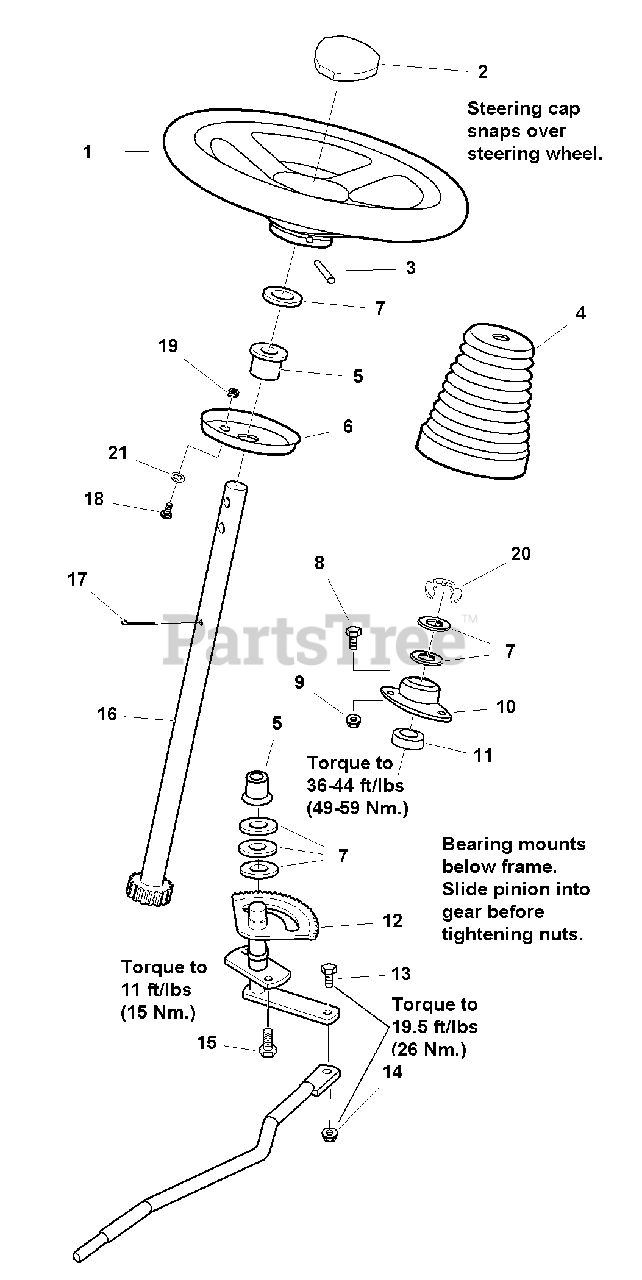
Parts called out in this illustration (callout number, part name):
1	STEERING WHEEL
2	CAP, Steering
3	ROLL PIN, 5/16 x 2.50
4	BELLOWS
5	BUSHING, Nylon
6	MOUNTING PLATE, Steering
7	WASHER, 3/4
8	SCREW, Flange Lock, 3/8-16 x 3/4
9	NUT, Whiz, 3/8-16
10	BEARING, Flange
11	SPACER
12	STEARING GEAR ASSEM
13	SCREW, 3/8-16 x 1 3/4
14	NUT, Flange Lock, 3/8-16
15	SCREW, Taptite, 5/16-18 x 3/4
16	STEER SHAFT
17	HAIRPIN CLIP
18	CARRIAGE BOLT, 5/16-18 x 1 1/4
19	NUT, 5/16-18
20	RING, Klipring
21	PUSHNUT, 5/16
